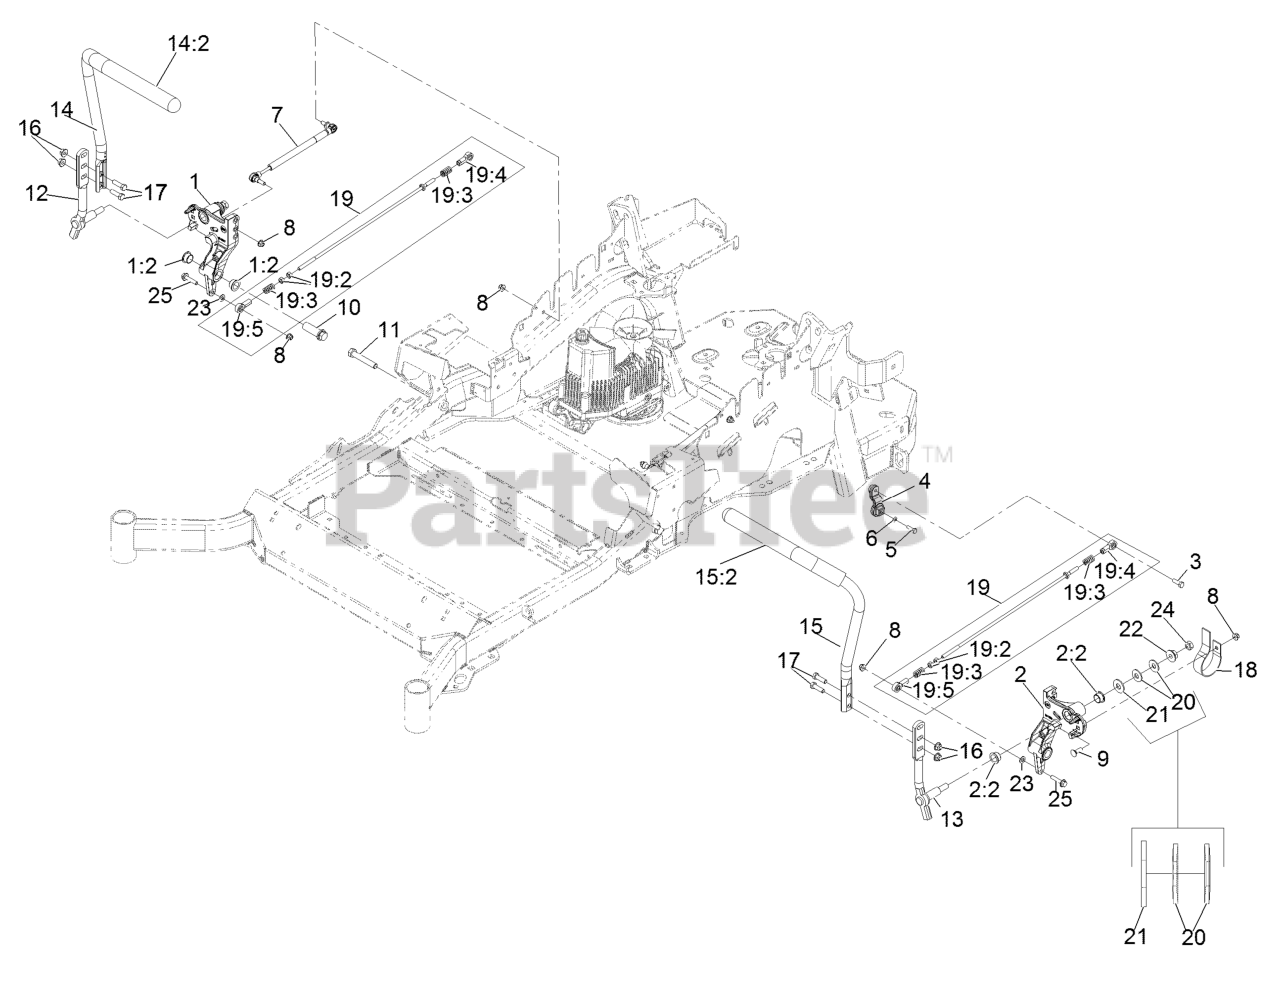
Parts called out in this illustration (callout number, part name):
1	RH MOTION CONTROL AND BUSHING ASM
1:2	BUSHING-FLANGE
2	LH MOTION CONTROL AND BUSHING ASM
2:2	BUSHING-FLANGE
3	SCREW-HH, THREAD LOCKING
4	ARM-CONTROL, PUMP
5	SCREW-HH
6	WASHER-SPRING
7	DAMPER-CONTROL, MOTION
8	NUT-HF, NI
9	BOLT-CARR
10	HUB-THREADED
11	SCREW-HH
12	LEVER-CONTROL MOTION, RH
13	LEVER-CONTROL MOTION, LH
14	RH STEERING HANDLE ASM
14:2	GRIP-LEVER, CONTROL
15	LH STEERING HANDLE ASM
15:2	GRIP-LEVER, CONTROL
16	NUT-HF, NI
17	SCREW-HH
18	SPRING-LEAF
19	PUMP LINKAGE REAR ASM
19:2	NUT-HEX
19:3	SPRING-COMPRESSION
19:4	BALLJOINT-LH
19:5	BALLJOINT-RH
20	WASHER-SPRING
21	WASHER-FLAT
23	WASHER-PLAIN
24	NUT-JAM
25	SCREW-HHF
